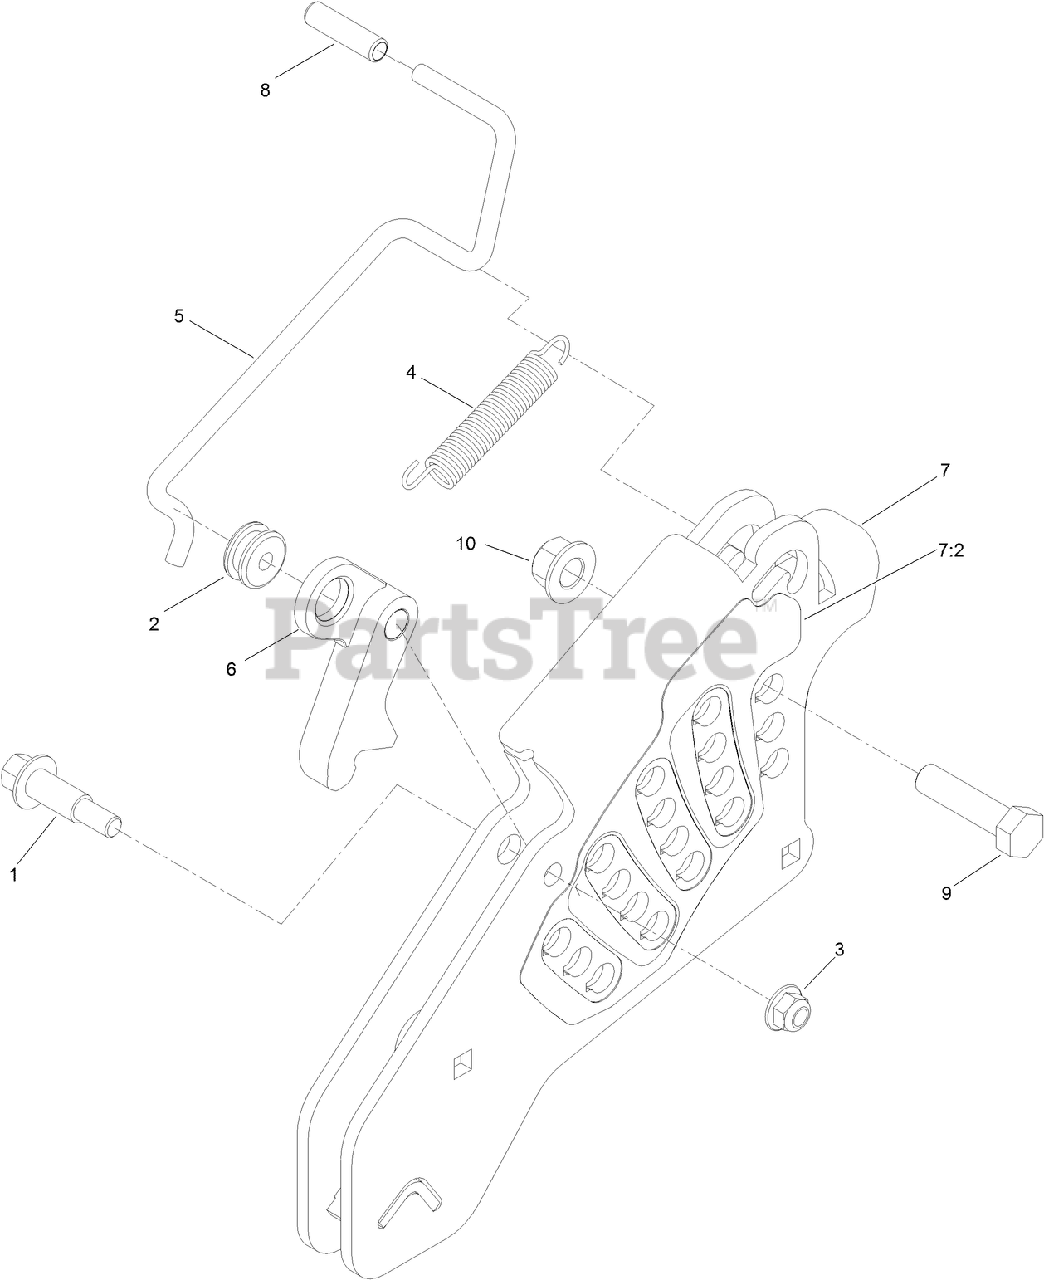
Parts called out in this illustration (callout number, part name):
1	BOLT-SHOULDER
2	GROMMET
3	NUT-HF, NI
4	SPRING-EXTENSION
5	ROD-LOCK, TRANSPORT
6	PAWL-TRANSPORT, HOC
7	HOC PLATE W/DECAL ASM
7:2	DECAL-HOC
8	GRIP-LEVER
9	SCREW-HH
10	NUT-LOCK
